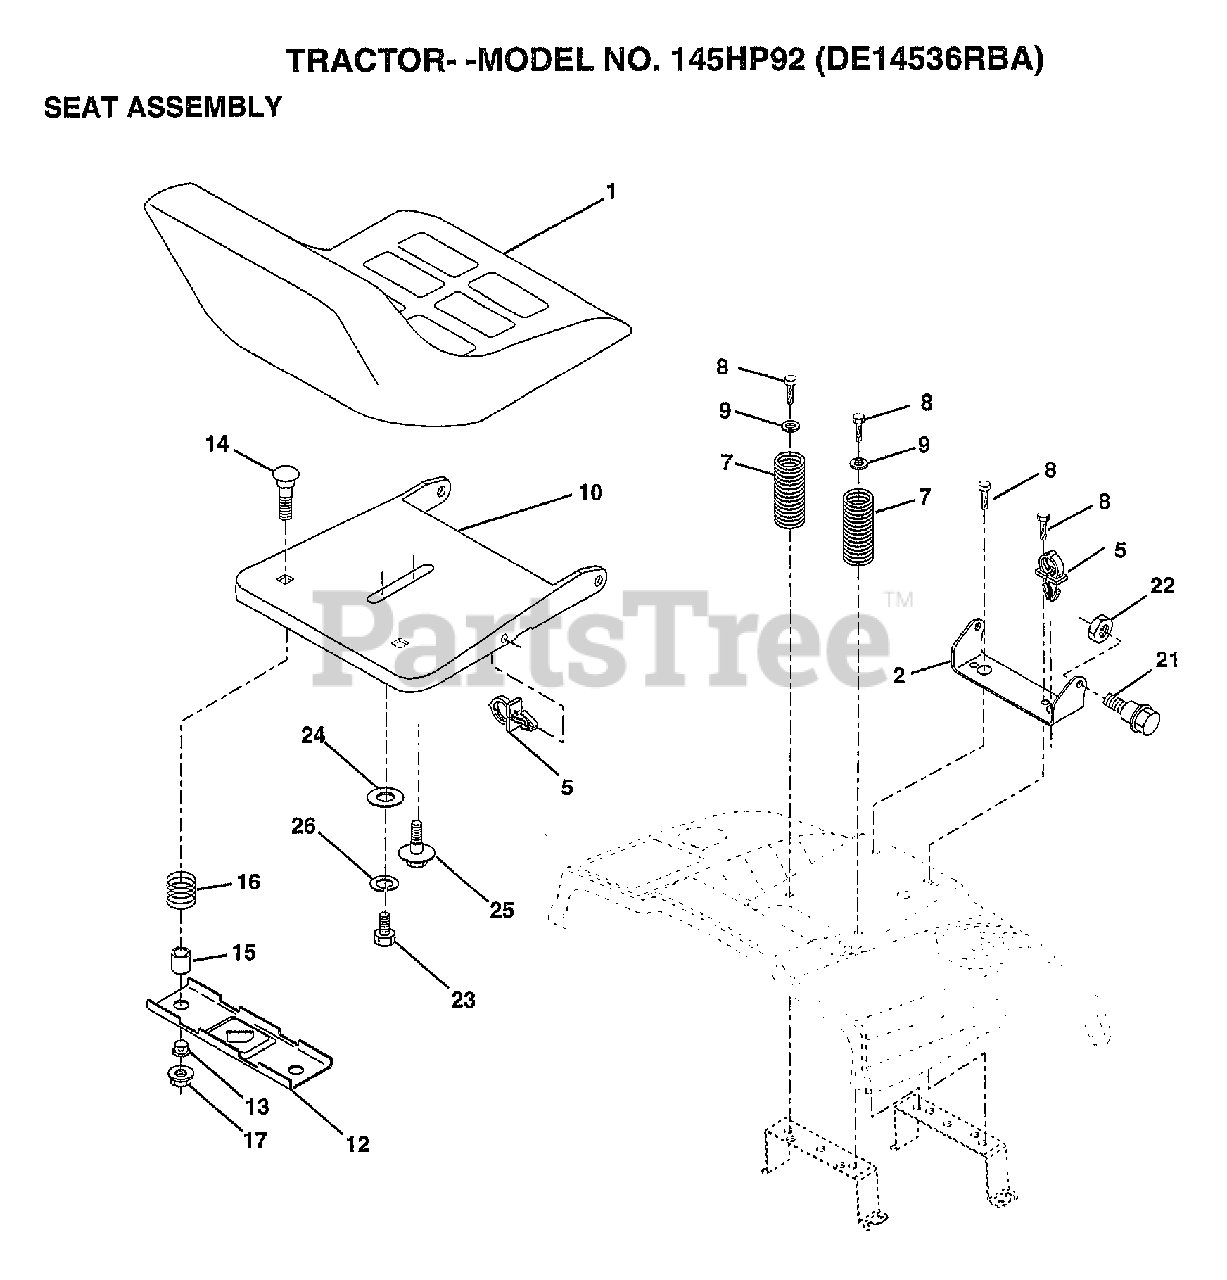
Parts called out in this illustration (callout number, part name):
2	BRACKET PVT SEAT
5	CLIP.PUSH-IN.HING
7	SPRING COMPRESSIO
8	SCREW GTV
9	WASHER
10	PAN-SEAT
12	BRKT SWITCH
13	BUSHING
14	BOLT-RD HD SQ NK
15	SPLIT SPACER
16	SPRING
21	"BOLT,SHOULDER"
22	NUT
23	BOLT
24	WASHER
25	"BOLT,SHOULDER"
26	LOCKWASHER
